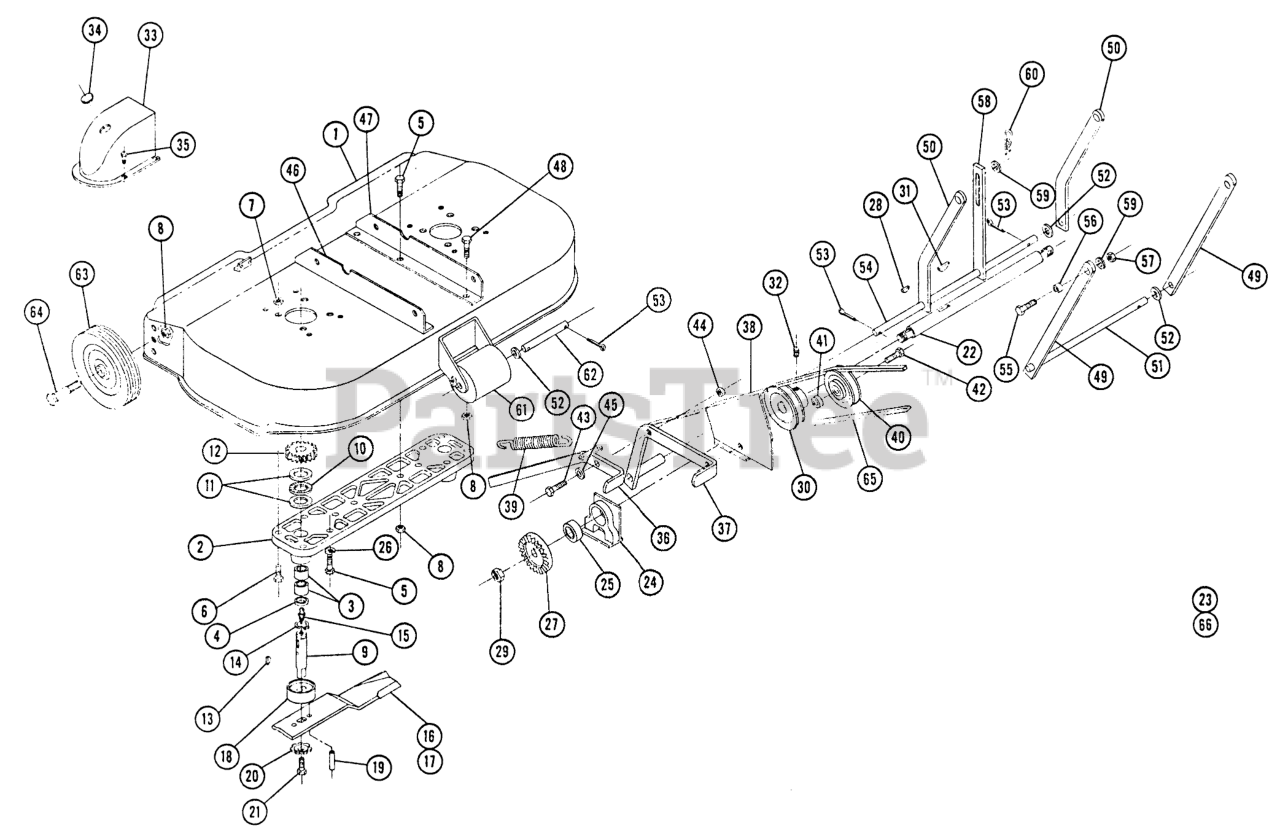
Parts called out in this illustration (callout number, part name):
1	Ass-y Deck
2	Twin Housing
5	Bolt 3/8-16 x 1
6	Bolt 5/16-18 x
7	Nut-Nylok
11	WASHER-THRUST
14	Snap Ring 3/4 I.D.
19	SPIROL ROLL PIN
21	Bolt 3/8-16 x 7/8
24	BEARING SUPPORT
26	Lockwasher
28	Key #5 Woodruff
29	Nut Hex 5/8-18 Thin
31	Key
32	Set Screw 5/16-18 x 5/16
34	PLUG BUTTON
35	SCREW
37	59027 1969 OPC
42	Bolt 3/8-16 x 7/8
43	Bolt-Hex 1/4-20
44	Nut-Nylok
45	Washer
46	Bracket Mtg. R.H.
47	Bracket Mtg. L.H.
48	Bolt 3/8-16 x 3/4
49	Link-Front
52	Washer
53	Cotter Pin
55	Bolt 3/8-16 x 1
57	Nut 3/-16 Elastic Stop
58	Bar Lift
59	Washer
60	Hairpin
64	Bolt-Shoulder
66	Decal
